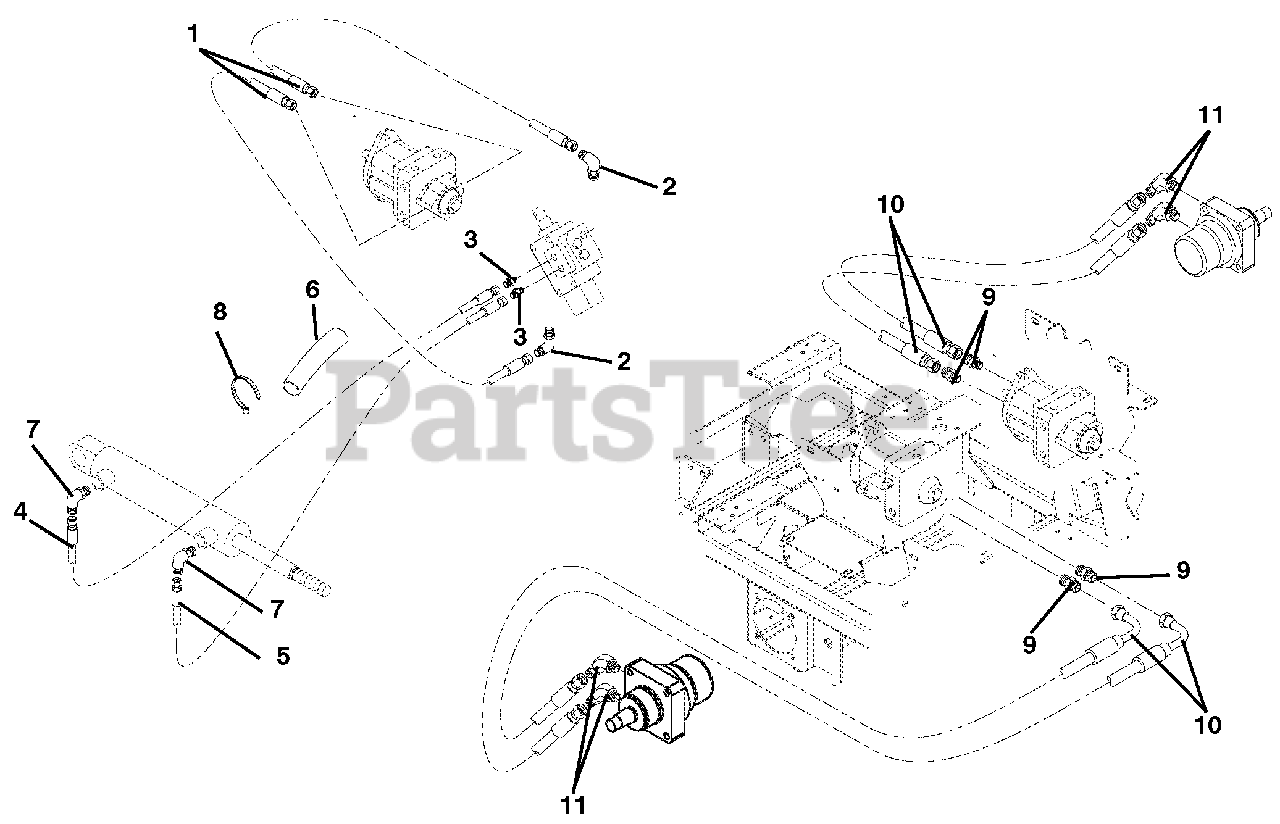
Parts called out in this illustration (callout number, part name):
1	Hose, Hydraulic
2	Hydraulic, Fitting Elbow
4	Hose, Hydraulic
5	Hose, Hydraulic
6	Sleeve Protective 24"
7	Fitting, Hydraulic
8	Cable Tie
9	Adapter, Face Seal 8 x 8 .50 O-Ring
10	Hose, Hydraulic .50
11	Adapter-Hydraulic Steel .875 to .75
